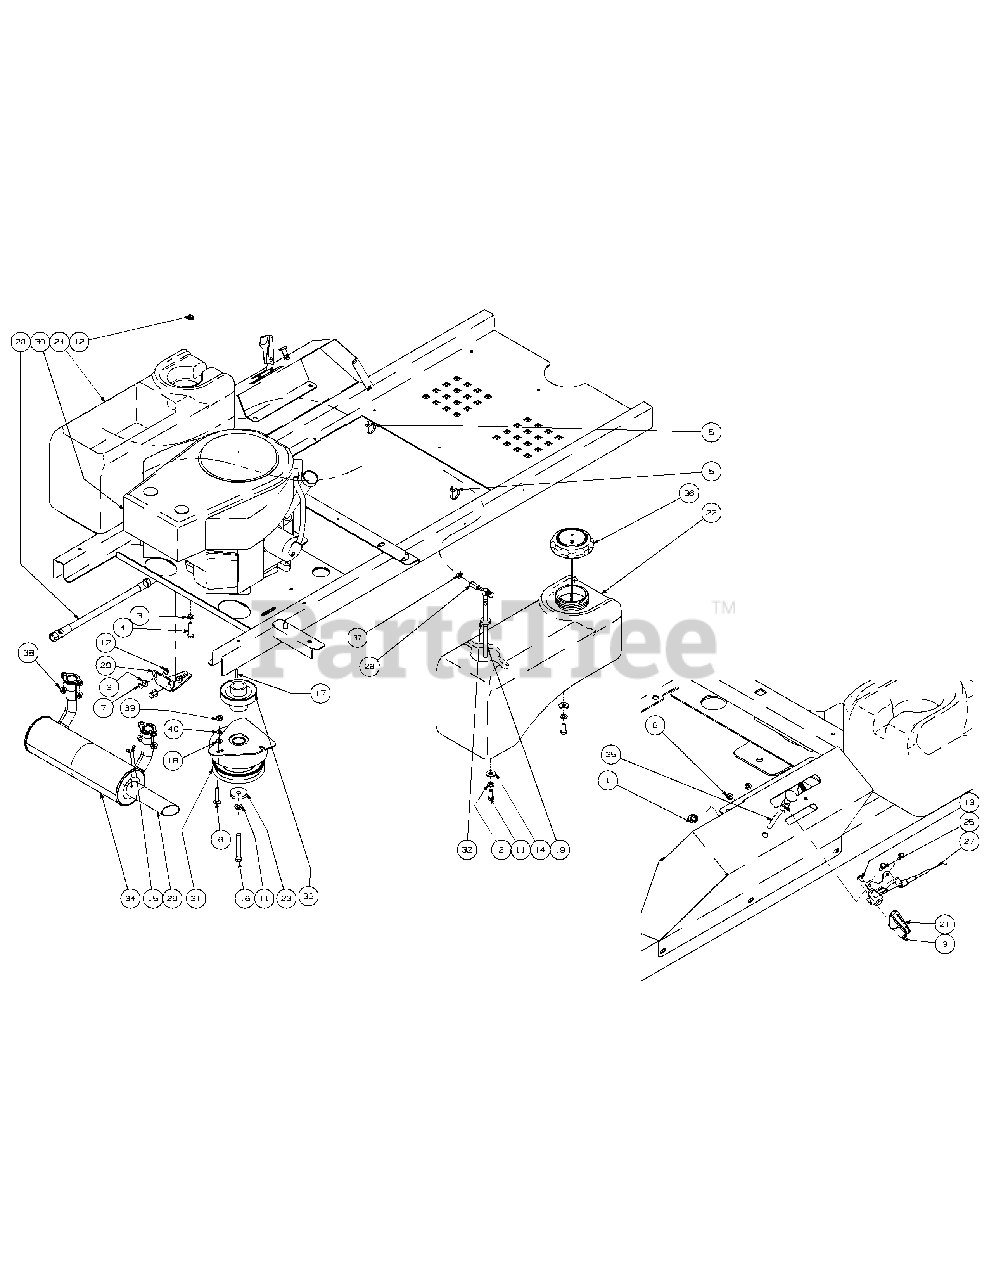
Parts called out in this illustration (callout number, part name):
1	Hex Jam Nut, 3/8-24
2	Lock Washer, 3/8 Zinc
3	Flat Washer, 5/16
4	Hex Cap Screw, 5/16-18 x 1-3/4
5	Cable Tie, 3/16 x .05 x 7.4
6	Carriage Bolt, 5/16-18 x 1.75
7	Hex Cap Screw, 5/16-18 x .75
8	Lock Nut, Nylon Insert, 10-32
9	Nut, w/ Star Washer
10	Hex Cap Screw, 3/8-16 x .88
11	Lock Washer, 7/16
12	Lock Nut, Hex Flange, 5/16-18
13	Machine Screw, 8-32 x .375
14	Flat Washer, .390 ID x 1.0 OD x .180
15	Screw, 8-32 x .375, Hex Washer
16	Hex Cap Screw, 7/16-20 x 3.00
17	Key, .25 x .25 x 2.00
18	Washer, 3/8 x .738 x .063
19	Fuel Pickup Fitting
20	Oil Drain Extension Hose
21	Throttle Control Knob
22	Fuel Tank
23	Flat Washer, 7/16 ID x 1.75 OD x .250
24	Utility Bin
25	Screw, #10-32 x 0.500
26	Exhaust Pipe
27	Throttle Control Cable
28	Hose, 1/4" Fuel Line
29	Clutch Retainer Assembly
30	23HP Kawasaki Engine
31	Electric Clutch
32	Fuel Tank Groment
33	Transmission Drive Pulley
34	Kawasaki Muffler
35	Choke Cable
36	Fuel Cap
37	Hose Clamp
38	Nut, M8-1.25, Hex Flange
39	Hex Nut, 5/16-18
40	Lock Washer, 5/16
